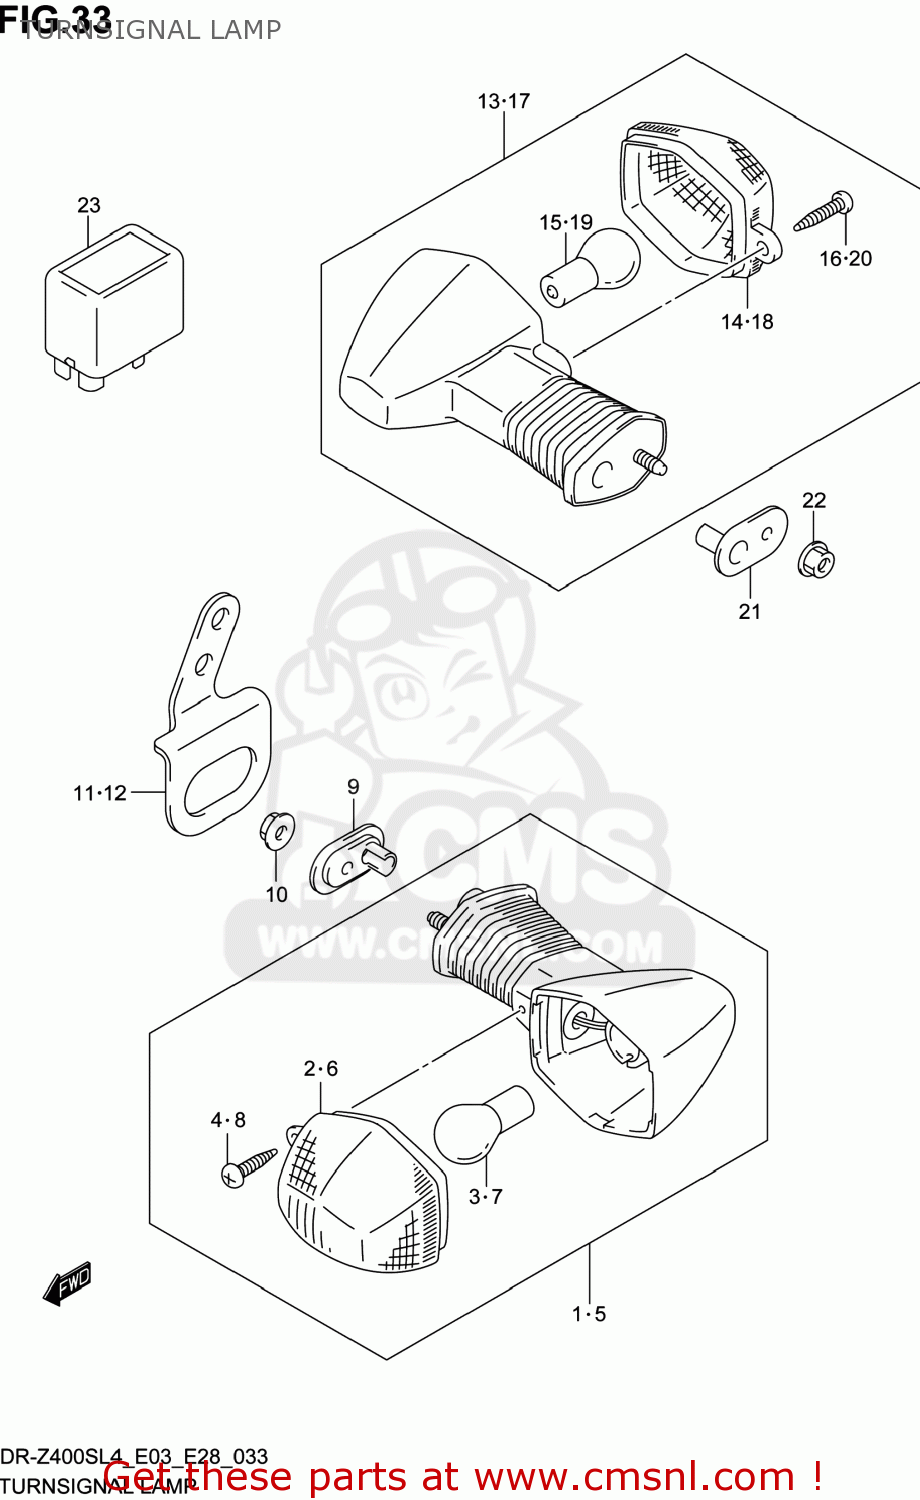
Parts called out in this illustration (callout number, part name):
1	LAMP ASSY,FR TURN SIGNAL,R
2	LENS
3	BULB(12V21W,AMBER)
4	SCREW
5	LAMP ASSY,FR TURN SIGNAL,L
6	LENS
7	BULB(12V21W,AMBER)
8	SCREW
9	PLATE,TURNSIGNAL LAMP
10	NUT
11	BRACKET,FR TURNSIGNAL,R
12	BRACKET,FR TURNSIGNAL,L
13	LAMP ASSY,RR TURNSIGNAL,R
14	LENS
15	BULB(12V21W,AMBER)
16	SCREW
17	LAMP ASSY,RR TURNSIGNAL,L
18	LENS
19	BULB(12V21W,AMBER)
20	SCREW
21	PLATE,TURNSIGNAL LAMP
22	NUT
23	RELAY ASSY,TURNSIGNAL LAMP
